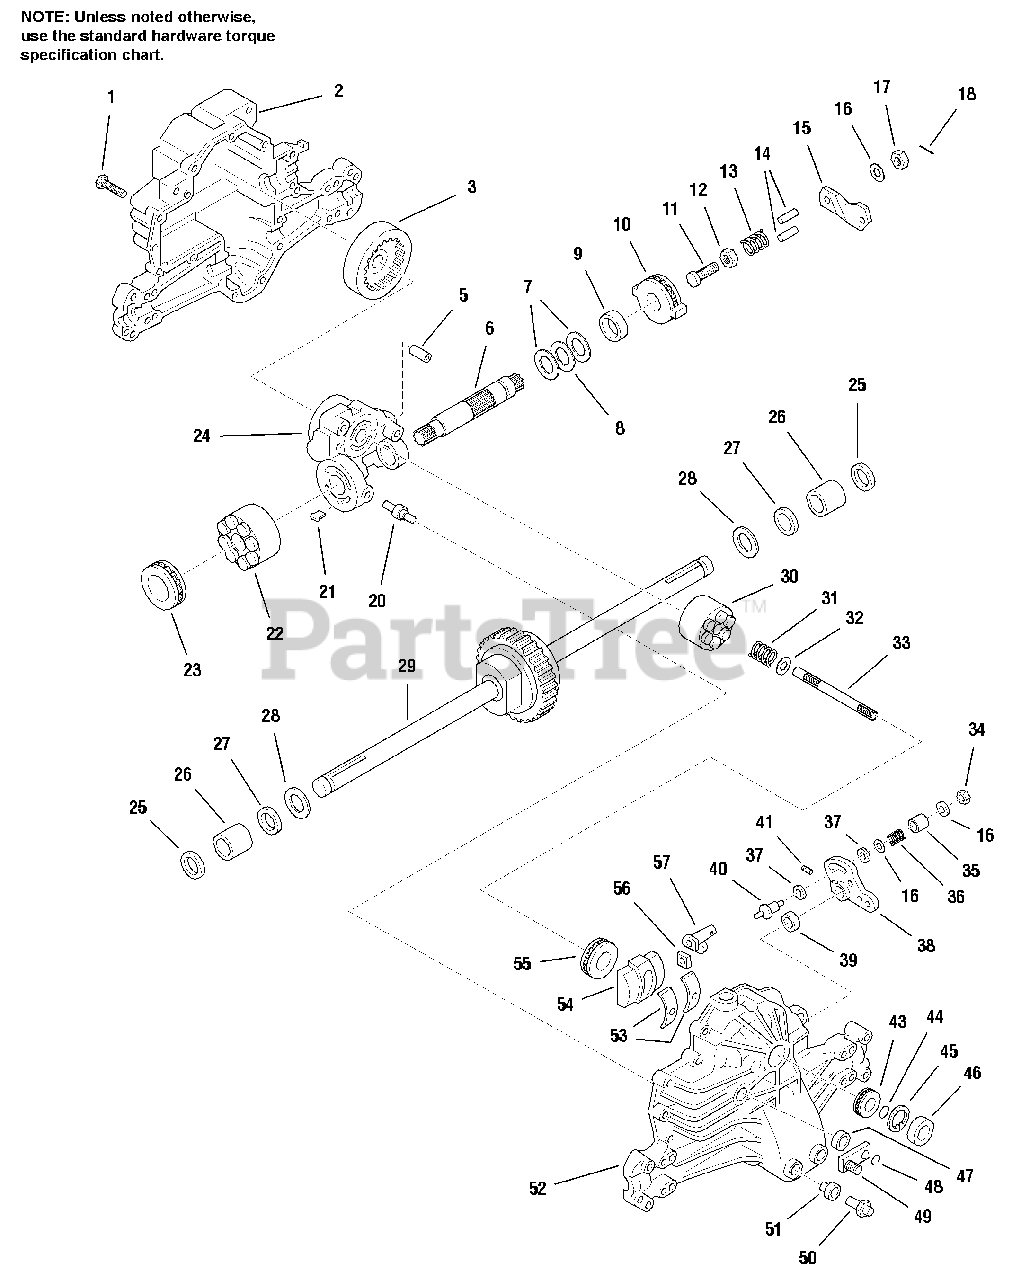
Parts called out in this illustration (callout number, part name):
1	BOLT, 1/4-20 x 1-3/8
2	HOUSING, Lower
3	OIL FILTER ELEMENT
6	SHAFT, Motor
8	RING, Retaining
9	SEAL-LIP .26 x .42 x .8
10	BRAKE ROTOR/STATOR KIT
11	BOLT, 5/16-18 x 1-3/4
12	NUT, Hex, Lock, 5/16-24
13	COMPRESSION SPRING
14	PIN-ACTUATING
15	ARM-ACTUATING
16	WASHER, 7/16 x 7/8 x 1/16
17	CASTLE NUT, 5/16-24
18	COTTER PIN
20	ACTUATOR-BYPASS
21	BYPASS PLATE
22	BLOCK-CYLINDER (MOTOR) ASSY.
23	BEARING, Thrust .42 x .68 x .16
24	CENTER SECTION ASSEMBLY
25	SEAL, Wiper
26	SLEEVE BEARING
27	SEAL 3/4 x 1-1/4 x 1/4
28	WASHER-3/4 x 1.5 x .13
29	DIFFERENTIAL ASSEMBLY
30	BLOCK-CYLINDER PUMP ASSY.
31	SPRING, Block
32	WASHER, Block Thrust
33	SHAFT, Input
34	NUT-HEX LOCK 5/16-24
37	PUCK, Dampener
38	ARM, Control
40	STUD, 5/16-24
43	BEARING, Shaft Ball
44	RING-WIRE, Retaining
45	RING, Retaining
47	SEAL-LIP 1.0 x .25 x .7
48	RING, Retaining
50	BREATHER ASSY.
51	BUSHING-VENT
52	UPPER HOUSING ASSEMBLY
53	BEARING, Cradle
54	SWASHPLATE, Variable
55	BEARING, Thrust .30 x .52 x .13
57	ARM, Trunnion
